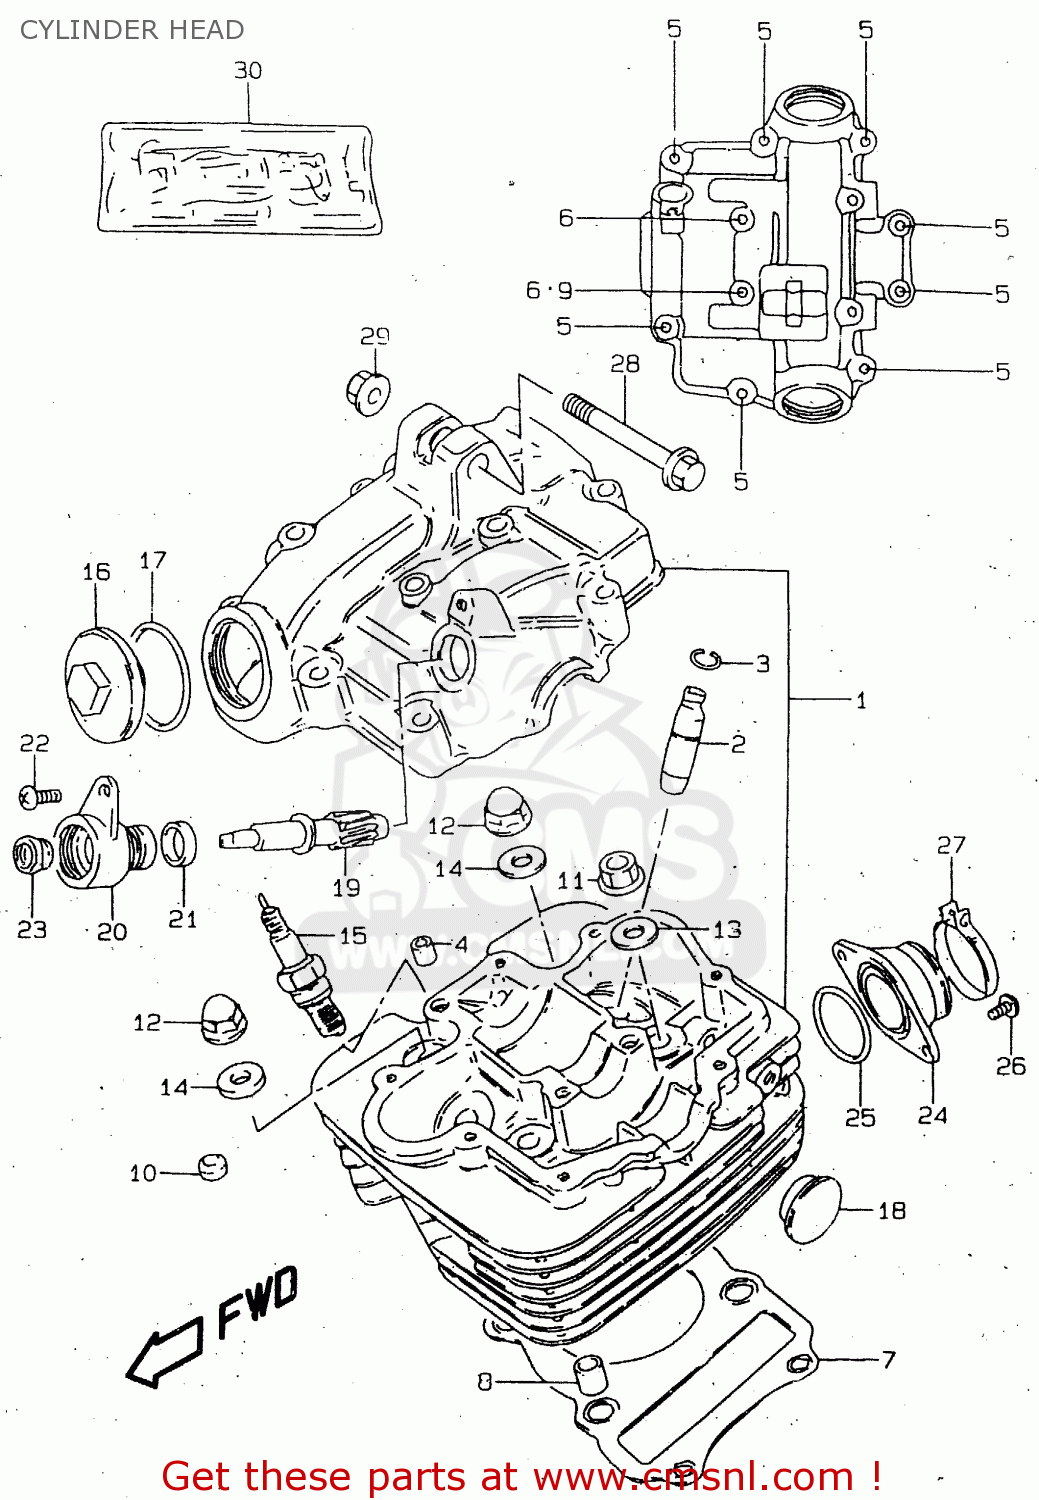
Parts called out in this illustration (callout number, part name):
1	HEAD ASSY,CYLINDER
2	GUIDE,VALVE
3	RING,SNAP
4	PIN(6.2X8X11)
5	BOLT
6	BOLT
7	GASKET,CYLINDER HEAD (NAS)
8	PIN
9	GASKET(5.8X13X1.2) (NAS)
10	PAD,CYLINDER HEAD
11	NUT
12	NUT
13	WASHER (8.5X19X2.3)
14	GASKET(8.5X17X2.3) (NAS)
15	SPARK PLUG D8EA
16	CAP,INSPECTION
17	O RING(D:3,ID:29.5)
18	PLUG(OD:22.5)
19	GEAR,TACHOMETER DRIVEN
20	SLEEVE,TACHOMETER DRIVE GEAR
21	SEAL,TACHOMETER DRIVEN
22	SCREW(5X12)
23	SEAL,OIL(5X12X8)
24	PIPE,INTAKE
25	O RING(D:2.4,ID:31.7)
26	SCREW
27	CLAMP
28	BOLT(8X50)
29	NUT
30	GASKET SET (NAS)
